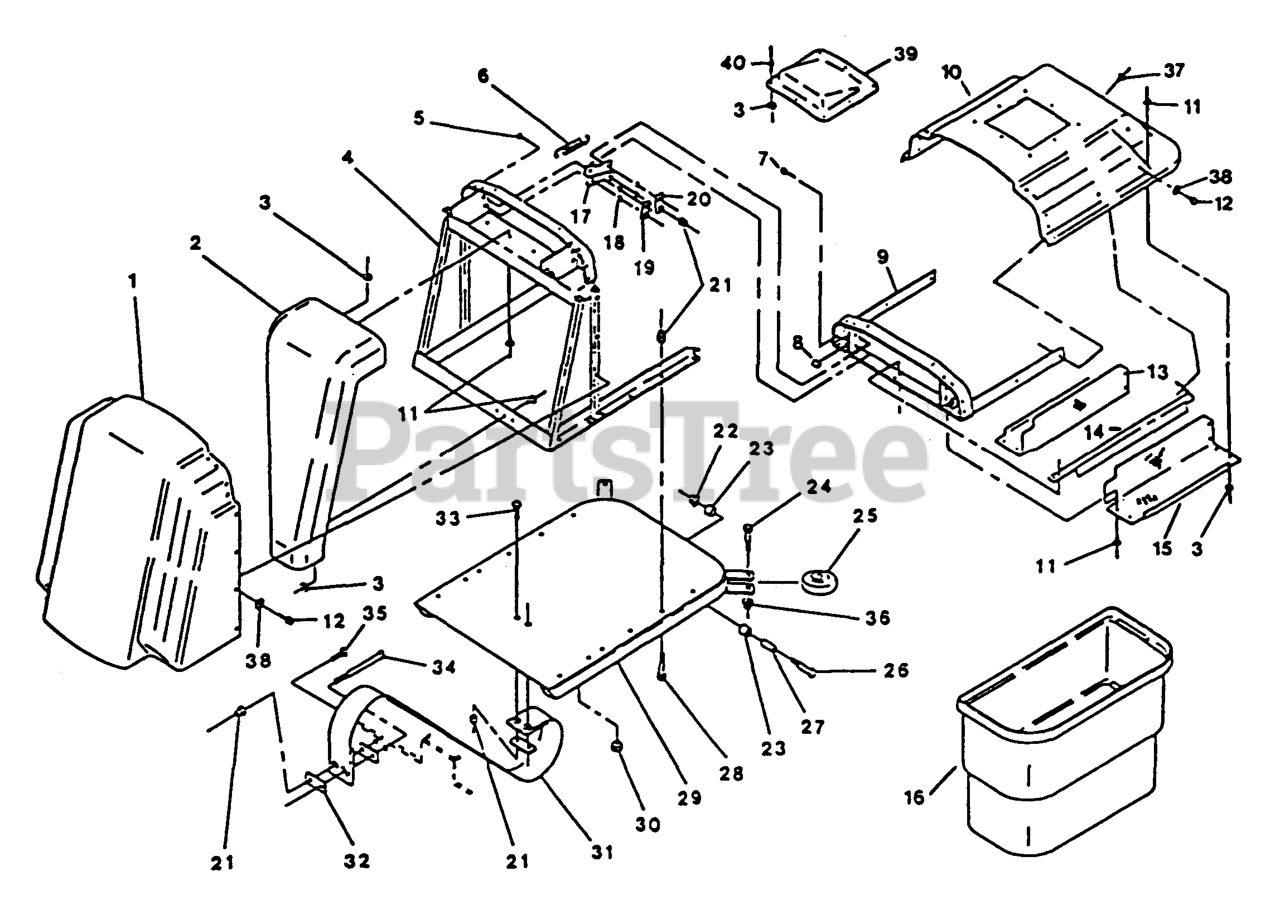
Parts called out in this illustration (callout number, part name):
6	SPRING,CATCHER LID
8	BUSHING,LID SPRING
10	TOP,GRASS CATCHER
13	SCREEN,PERFORATED RH PNT
15	SCREEN,PERFORATED LH PNT
17	LINK,HINGE PLTD
23	SLEEVE-BEARING
25	WHEEL,RUBBER
27	BUSHING,BOX PIVOT
31	STRAP,BOX RESTRAINT
32	CLAMP,STRAP
33	Bolt, Carriage 1/4-20 X 1
37	Rivet, 3/16 X 1/4
39	WINDOW,GRASS CATCHER
